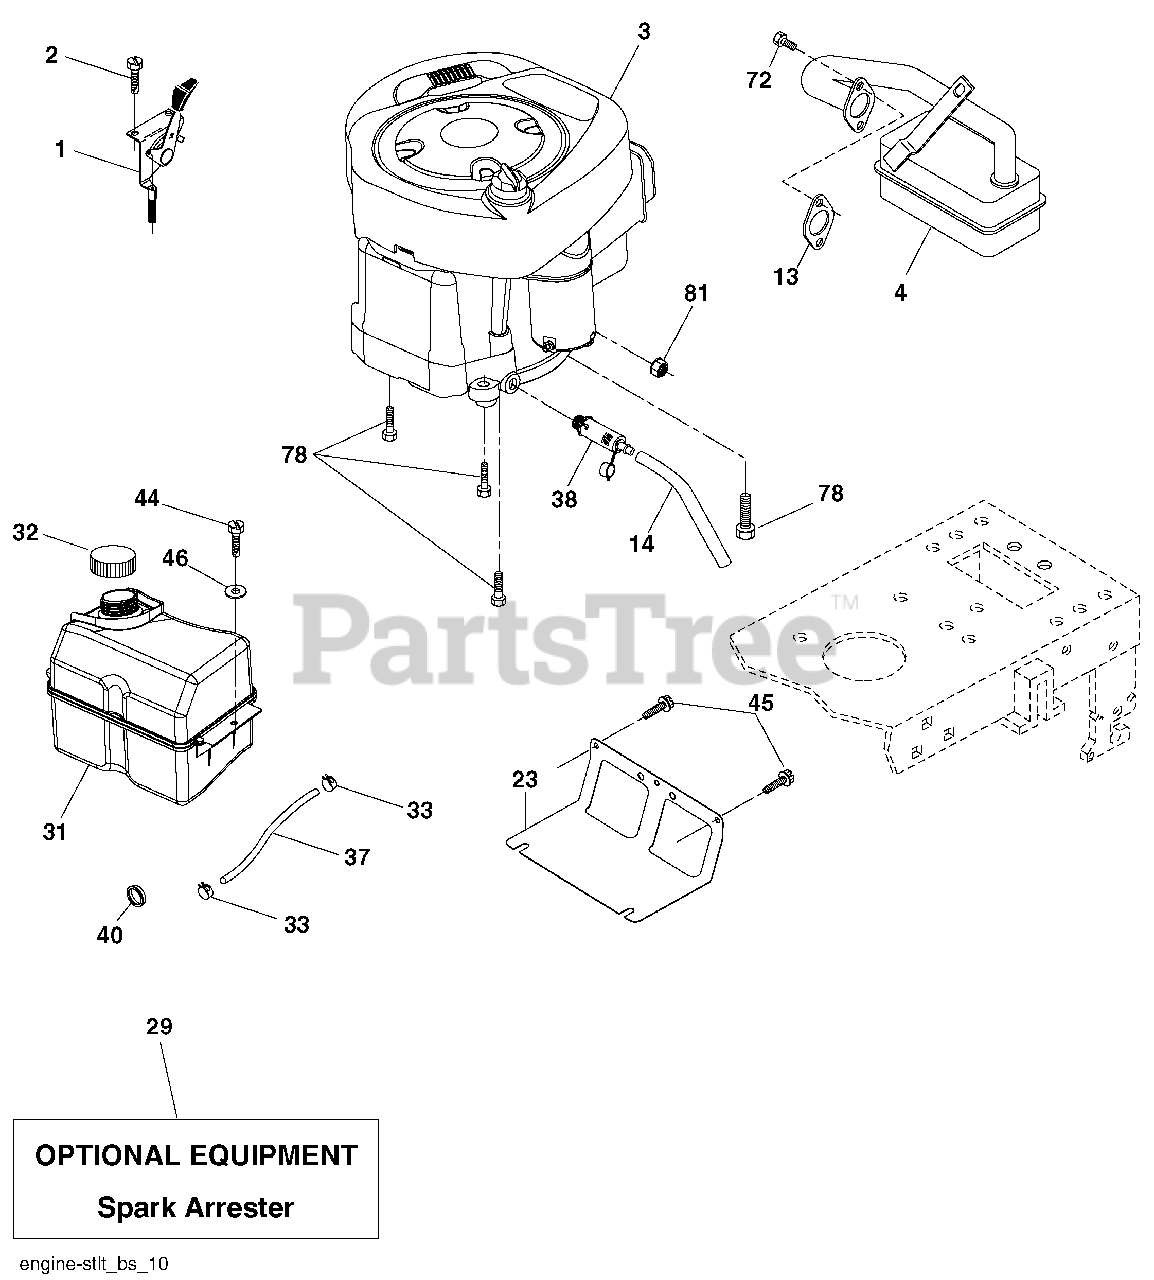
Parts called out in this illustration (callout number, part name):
1	Control Th/ch Flag
2	Screw Hex Thd Cut 1/4-20 x 1/2
4	Muffler Exhaust B&S
13	Gasket Eng 1 313 Id Tin Plated
14	Tube Drain Oil Easy
23	Shield BRN/DBR Guard
29	Kit Spark Arrestor (Flat Scrn)
31	Tank Fuel Front
32	Cap Asm Fuel
33	Clamp Hose
37	Line Fuel 20"
38	Plug Drain Oil
40	Bushing Snap
44	Screw Thdrol 1/4-20 x 3/4
45	Screw Hex Wsh Thdrol 3/8-16
46	Washer 9/32 x 7/8 x 16 Ga.
72	Screw Socket Hd 5/16-18 x .75
78	Screw 3/8-16 x 1-1/4
81	Nut Keps Hex 1/4-20 unc
